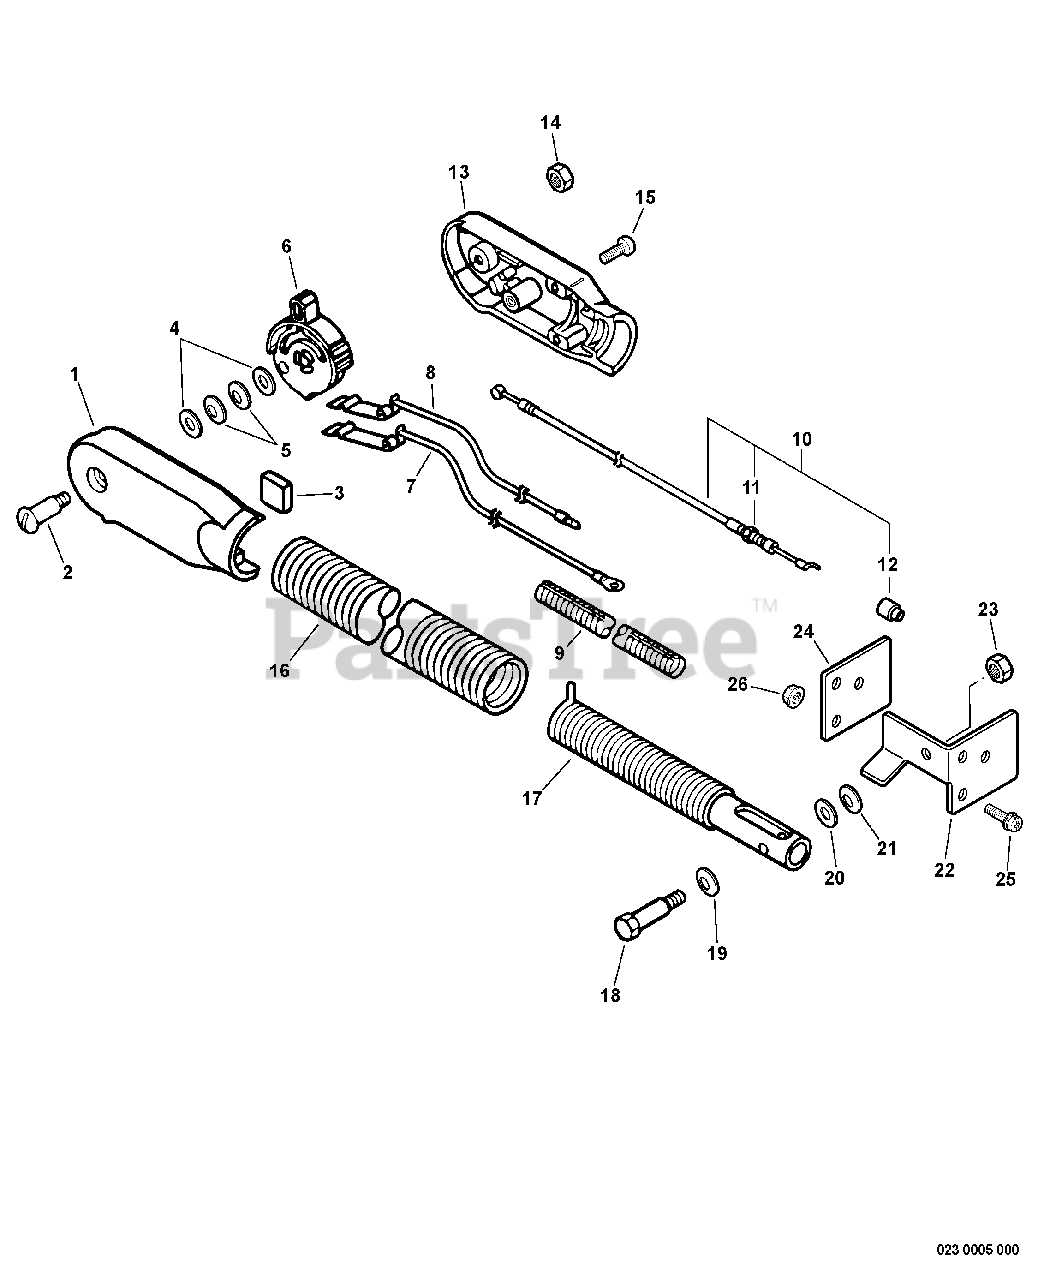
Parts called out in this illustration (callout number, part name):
1	HANDLE, CONTROL - LEFT
2	SCREW - 4
3	PAD, FOAM
4	WASHER - 6
5	WASHER - SPRING
6	LEVER, THROTTLE CONTROL
7	LEAD - GROUND
8	LEAD - IGNITION
9	TUBE, PROTECTIVE - CORRUGATED
10	THROTTLE CABLE ASSY
11	LOCKNUT - 6
12	CAP, DUST
13	HANDLE, CONTROL - RIGHT
14	LOCKNUT - 4
15	SCREW - 5X20
17	TUBE, SPRING
18	BOLT - 6
19	WASHER - SPRING
20	WASHER - 8
21	WASHER - 8
22	BRACKET
23	LOCKNUT - 1/4"
25	SCREW - 5X16
26	NUT - 5 -- FLANGE
